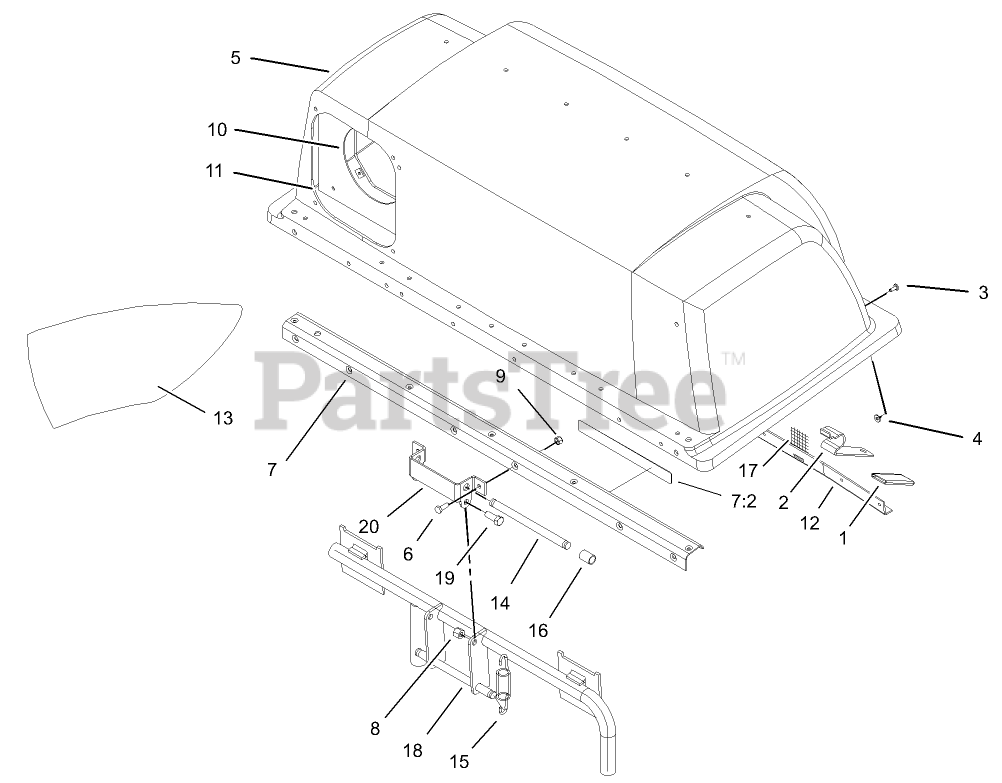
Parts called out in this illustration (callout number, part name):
2	LATCH-BAGGER, TOP
3	RIVET-BLIND
4	WASHER-FLAT
5	TOP-BAGGER
6	SCREW-HH
7	STIFFENER ASM
7:2	DECAL-CAUTION
8	NUT-LOCK, NI
9	NUT-LOCK, NI
10	CLAMP-SEAL
11	SEAL-CHUTE
12	SUPPORT-SCREEN
13	CHUTE-BAGGER
14	PIN-SPRING
15	SPRING-EXTENSION
16	SPACER
17	SCREEN-BAGGER
18	FRAME ASM
19	SCREW-HH
20	HINGE-BAG, TOP
